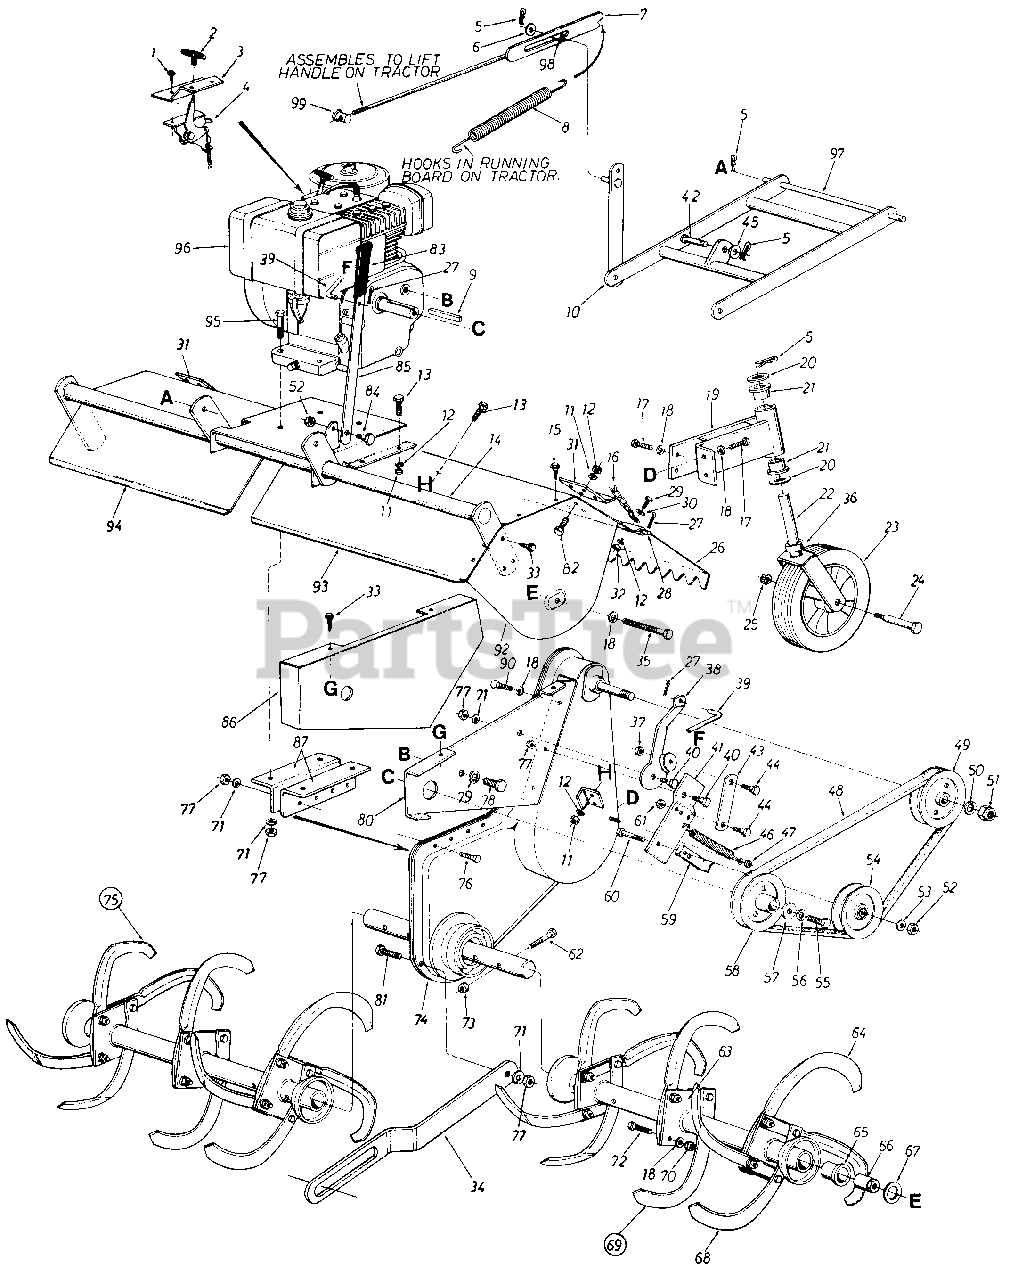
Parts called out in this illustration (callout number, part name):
1	Hex Wash. Hd. Self-Tap Scr. #8 x .50" Lg.
2	Throttle Control Knob-
3	Throttle Control Bracket
4	Throttle Control Ass'y.Comp.
5	Internal Cotter Pin
6	Fl-Wash. 1/2" I.D. x .93" O.D.
9	Sq. Key 1/4 " x 1/4 " x 2.00" Lg.
12	L-Wash. 1/4" I.D.
13	Hex Bolt 1/4-28 x .62" Lg.
16	#2 Dog Chain x 20" Lg.
17	Hex Wash. Hd. Self-Tap Scr. 318-24 x .75" Lg.
18	L-Wash. 3/8" I.D.
21	Flange Bearing 3/4" I.D. x 1.00" O.D.
24	Shoulder Bolt .623" I.D. x 3.62" Lg.
25	Hex Cent. L-Nut 7/16-14 Thd.
28	L.H Flap Rod
29	Hex Bolt 1/4-20 x .62" Lg.
30	Fl-Wash. 1/4" I.D.
33	Hex Wash. Hd. Self-Tap Scr. 1/4" x.62" Lg.
36	Spacer.752" I.D. x 1.25"O.D.
37	Hex Cent. L-Nut 5/16-18 Thd.
40	Shoulder Bolt 7/16" Dia. x 1.75" Lg.
45	Fl-Wash. .50" I.D. x 1.0" O.D. x .06
46	Extension Spring .62" O.D. x 6.12" Lg.
47	Hex Crown Nut 3/8-24 Thd.
48	"V"-Belt 1/2" x 43" Lg. (Kevlar)
49	1/2" "V"-Pulley 4.75" O.D. x .625" Bore
50	L-Wash. 5/8" I.D.*
51	Hex Ins. L-Nut 5/8-18 Thd.
52	Hex Cent. L-Nut 3/8-16 Thd.
53	Fl-Wash. 3/8" I.D.
54	Idler Pulley 4.0" O.D.
55	Hex Bolt
56	L-Wash. 7/16" I.D.
57	Fl-Wash. 7/16" I.D. x 1.38" O.D.
58	1/2" V"-Pulley .475" O.D. x 1.00" Bore
61	Hex Cent. L-Nut 5/16-18 Thd.
62	Hex Bolt 7/16-14 x 2.00" Lg.
66	Spacer
67	Thrust Wash. 1/2" I.D. x 1.55" O.D.
71	L-Wash. 5/16" I.D.
72	Hex Bolt 3/8-24 x 1.5" Lg.
73	Hex Cent. L-Nut 7/16-14 Thd.
77	Hex Nut 5/16-18 Thd.
78	Hex Bolt 1/2-20 x .88" Lg. (Grade 5)
79	L-Wash. 1/2" I.D.
80	Clutch Support Bracket
81	Shld. Bolt .435 Dia. x .265 5/16-18 Thd.
82	Hex Bolt 1/4-28 x .75" Lg.
83	Plastic Grip
84	Shoulder Bolt .498 Dia. x .212 Lg.
96	8 H.P. Engine
97	Hitch Rod
98	Push Bar Sleeve .503" I.D. x .624 " O.D.
99	Ferrule
